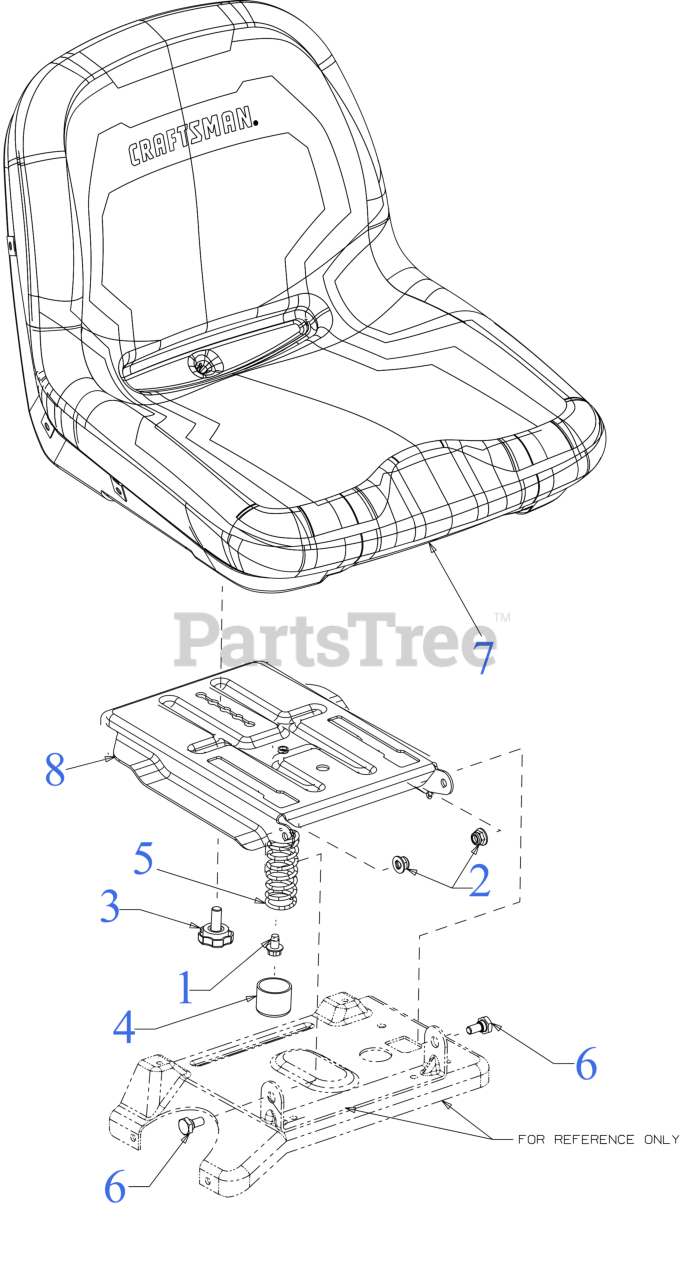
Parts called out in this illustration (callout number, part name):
1	SCREW 5/16-18 x .500
2	FLANGE LOCK NUT 5/16-18
3	SEAT ADJUSTMENT KNOB
4	SEAT SPRING CAP
5	SEAT SPRING
6	SHOULDER SCREW .437
7	SEAT (HI/CRAFTSMAN/FLAT)
7	LH & RH ARMREST KIT
